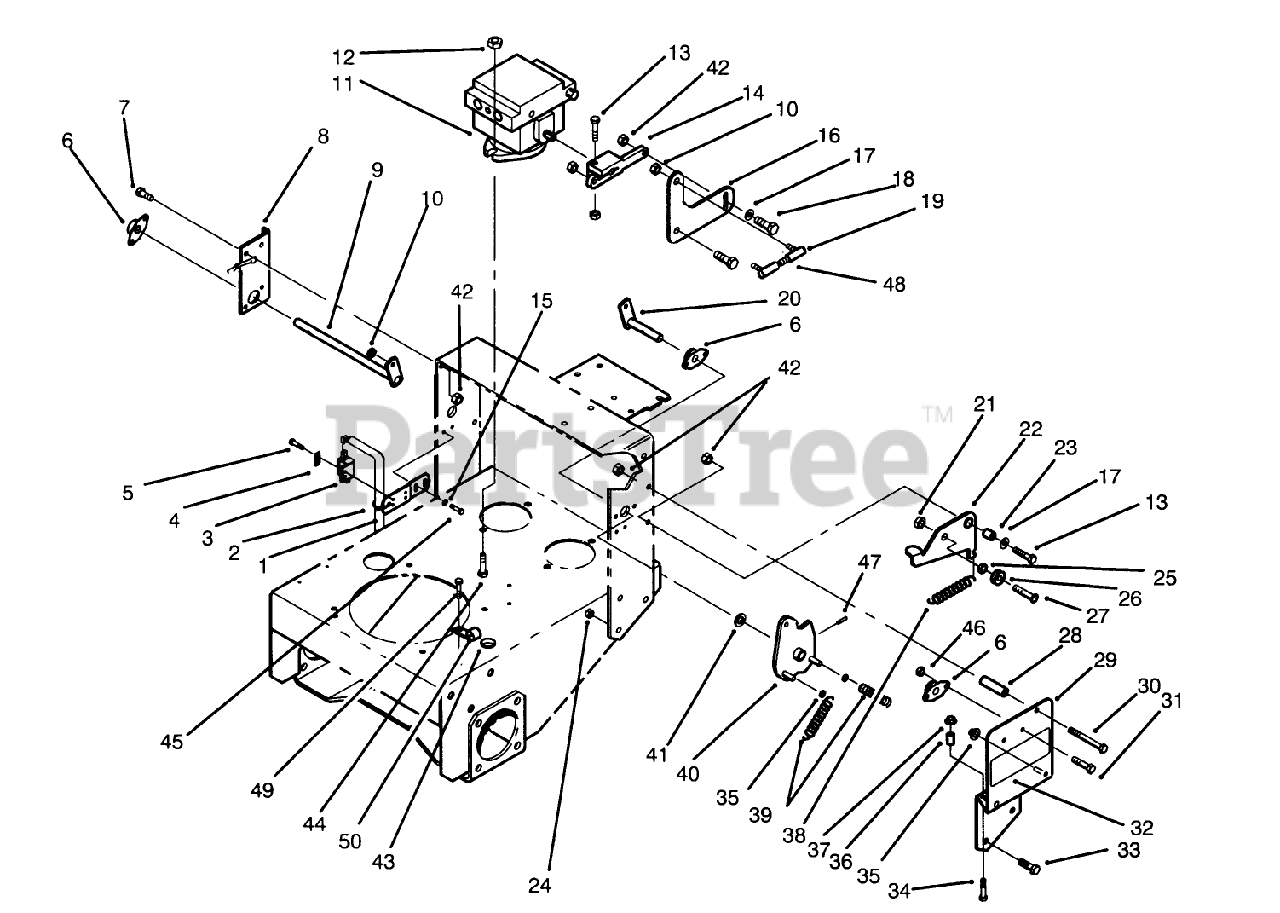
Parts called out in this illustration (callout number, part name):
1	NEUTRAL BRACKET B
2	TIE-CABLE
3	SWITCH-POLE, SINGLE
4	PLATE-SWITCH
5	SCREW-TAPTITE
6	SIDE FLANGE BEARING ASM
7	SCREW-HH
8	Bracket-Bushing
9	RH LEVER WA
10	NUT-LOCK, NI
11	HYDRAULIC PUMP
12	NUT-HF
13	SCREW-HH
14	ARM-PUMP
15	WASHER-FLAT
16	FOLLOWER ARM B
17	WASHER-PLAIN
18	SCREW-HH
19	JOINT-BALL
20	LH LEVER WA
21	NUT-LOCK, NI
22	Detent Arm Assembly L.H.
23	BUSHING-ARM, DETENT
24	NUT-LOCK, NI
25	SPACER-BEARING
26	BEARING-BALL
27	SCREW-HSBH
28	STOP-REVERSE
29	LEFT BRACKET WA R
30	SCREW-HH
31	SCREW-HH
32	DECAL-HYDRO
33	SCREW-HH
34	SCREW-HH
35	NUT-PUSH
36	SPACER-TUBULAR
37	NUT-LOCK, HHF
38	SPRING-DETENT
39	SPRING-EXTENSION
40	LH PIVOT ARM WA RO
41	WASHER-THRUST
42	NUT-LOCK, NI
43	GROMMET
44	SCREW-HH
45	Screw
46	NUT-LOCK, NI
47	PIN-ROLL, SLOTTED
48	BALL JOINT ROD
49	SCREW-HWH
50	CLAMP-R
51	NUT-PUSH IN
52	STOP BRACKET
